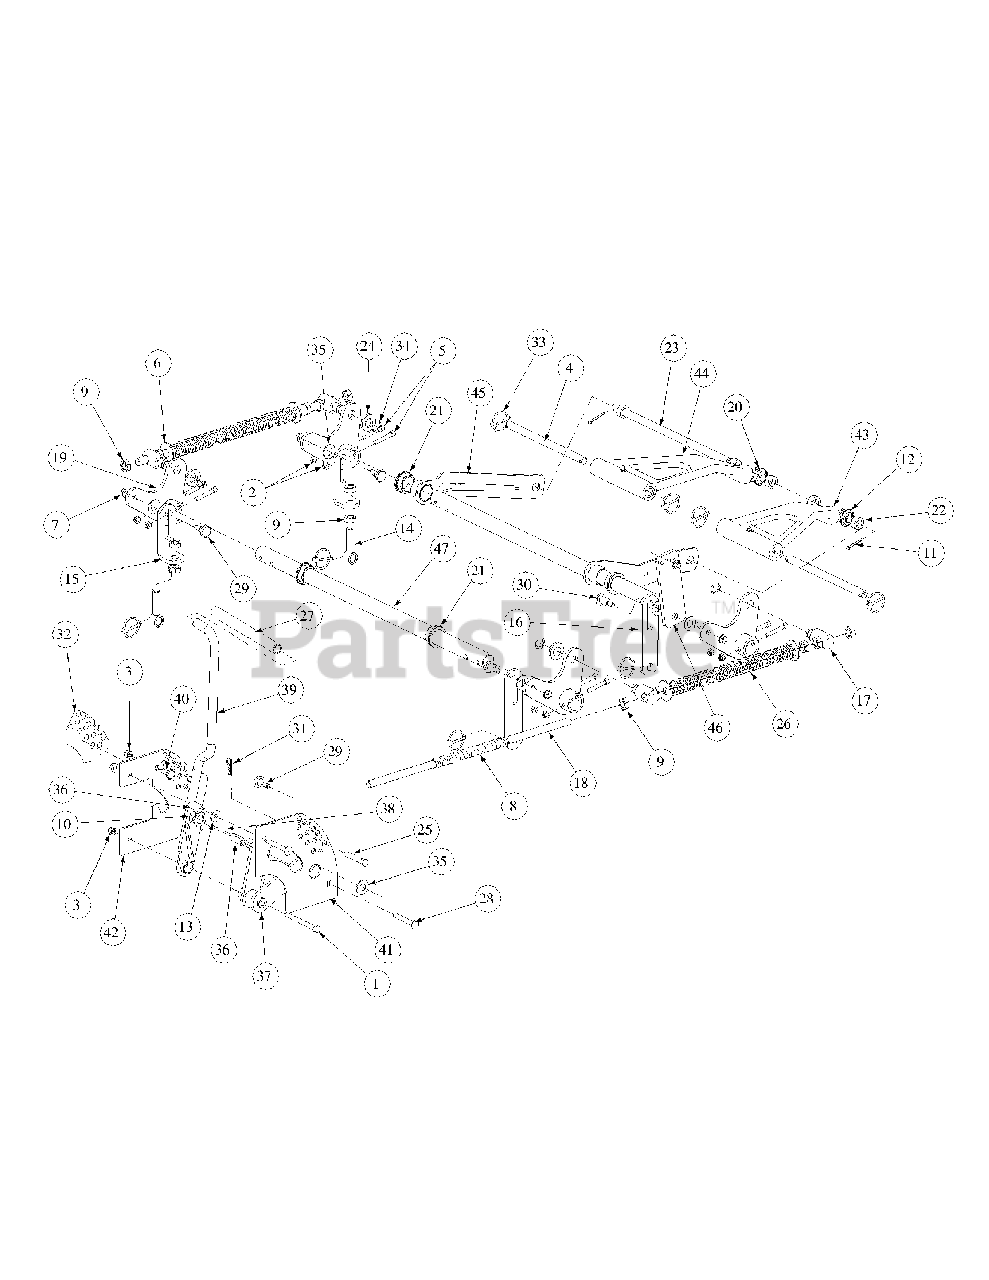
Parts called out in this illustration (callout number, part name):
1	Hex Cap Screw, 3/8-16, 3.75
2	Nut, 5/16-18, Nylock
3	Nylock Insert Lock Nut, 3/8-16
4	Deck Lift Link Rod
5	Socket Head Screw, 5/16-18 x 2
6	Flat Washer, 5/8
7	Hex Nut, Flange Lock, 3/8-16
8	Hose, 5/8 ID 13/16 OD, 8" LG
9	Jam Nut, 5/8-11
10	Flat Washer, .06, .776, 1.25
11	Cotter Pin, 3/16 x 1-1
12	Male Rod End, Right Hand
13	Idler Washer
14	Eye Bolt, 5/8ID
15	Eye Bolt Mount Link, 5/8 ID
16	Deck Link
17	Ferule Lift
18	Lift Connector Rod
19	Bellecrank Weldment Lift
20	Jam Nut, 5/8-18
21	Hex Flange Bearing, 1.25 ID
22	Spacer, .630 x 1.06 x .440
23	Front Lift Link, Rod Mount
24	Spacer, .812 ID x .218 Lg.
25	Clevis Pin, .437 Dia. x 2.625 Lg.
26	Lift Compression Spring
27	Lift Handle Grip
28	Carriage Bolt, 3/8-16, 2.75
29	Shoulder Screw, 0.625 OD x .437 Lg.
30	Shoulder Screw, 0.625 OD x .830 Lg.
31	Cotter Pin, .148 x 3.00
32	Decal Height Indicator
33	Linch Pin, 3/16 Dia.
34	E Clip, 3/4 Dia.
35	Nylon Flat Washer, 5/8
36	Spacer, .39 ID x .63 OD x 1.442
37	Lift Pivot Assembly
38	Lift Handle Spring
39	Lift Handle Assembly
40	Shoulder Screw, .50 OD x 0.270, 3/8-16
41	Outer Lift Index Plate
42	Inner Lift Index Plate
43	Trail Link Assembly, w/ brg Right Hand
44	Trail Link Assembly, w/ brg Left Hand
45	Front Frame Strut Assembly
46	Lift Link Adjustment
47	Deck Lift Shaft
